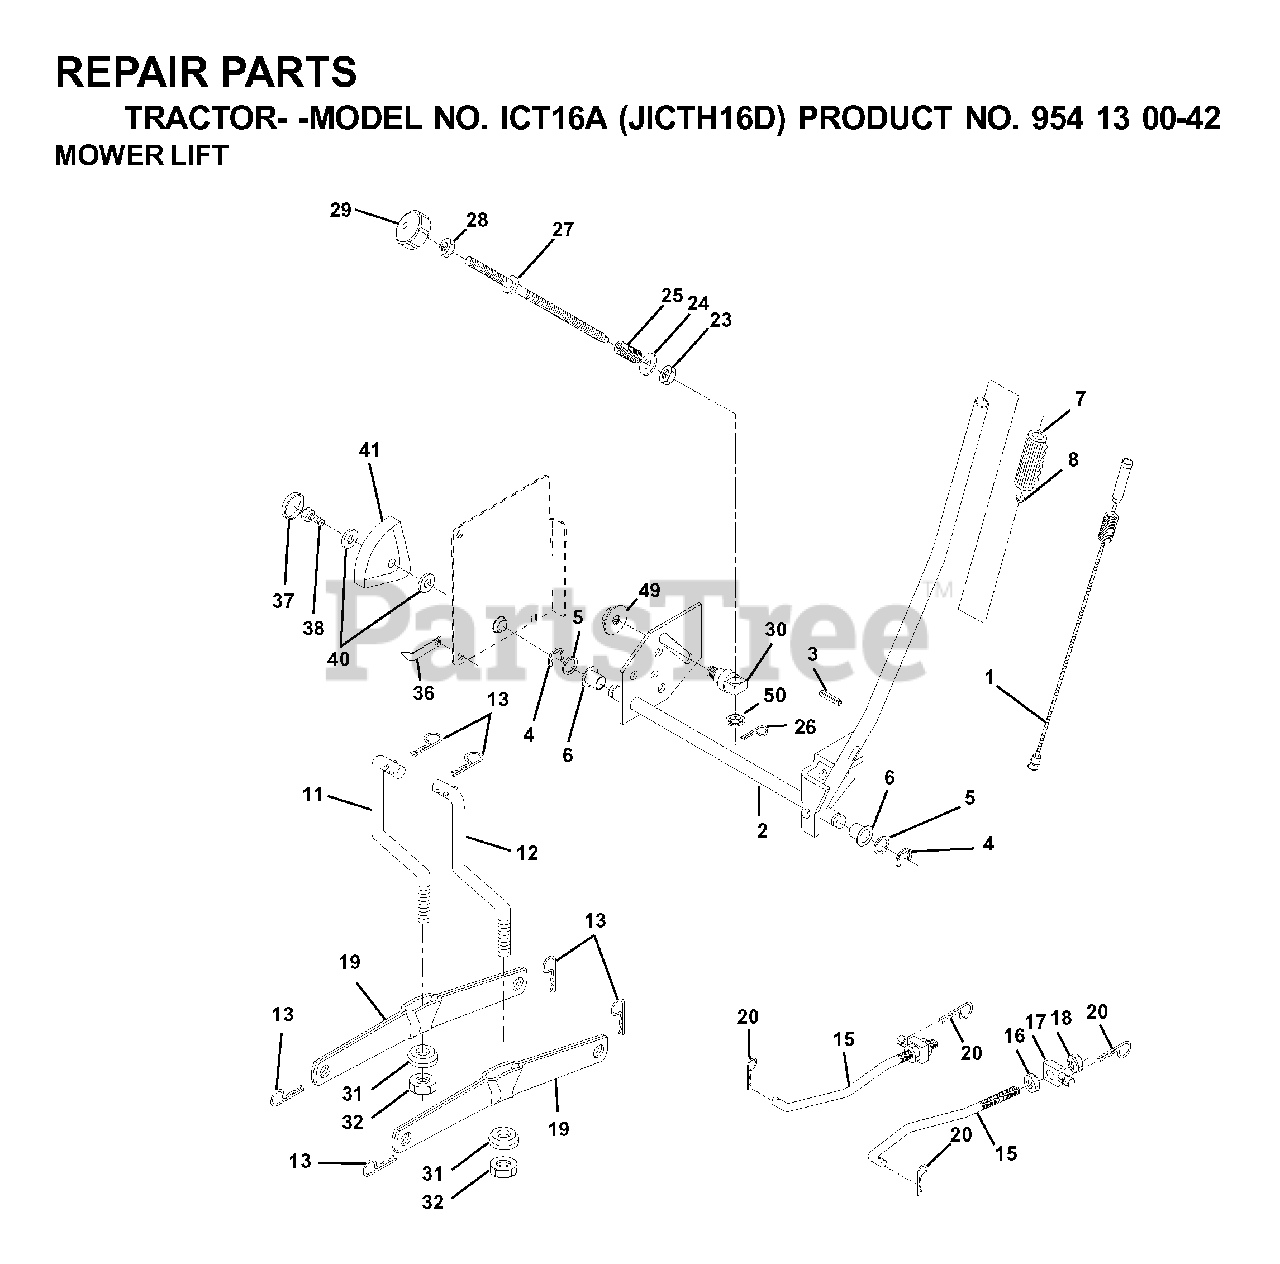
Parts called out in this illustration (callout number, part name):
1	WIRE ASM INNER W/ PLUNGER LT
2	SHAFT ASM R HANDLE
3	PIN GROOVE
4	RETAINING RING LT
6	BEARING.NYLON
7	GRIP HANDLE
8	PLUNGER BUT KIT
11	LINK
12	LINK
13	RETAINER-SPRNG RB
15	LINK.SUSPENSION.FRONT
16	NUT
17	TRUNION
18	NUT
19	ARM.REAR.SUSPENSION
20	SPRING RETAINER
25	SPRING**
26	RETAINER CLIP
27	ROD ADJ LIFT
28	NUT
29	KNOB INF 3/8-16
31	BEARING PIVOT
32	NUT CROWNLOCK 3/8-24
36	POINTER, HEIGHT INDICATOR
37	PLUG,HOLE
38	SCREW 5/16-18X1
41	HEIGHT INDICATOR
49	NUT
50	NUT PUSH M
